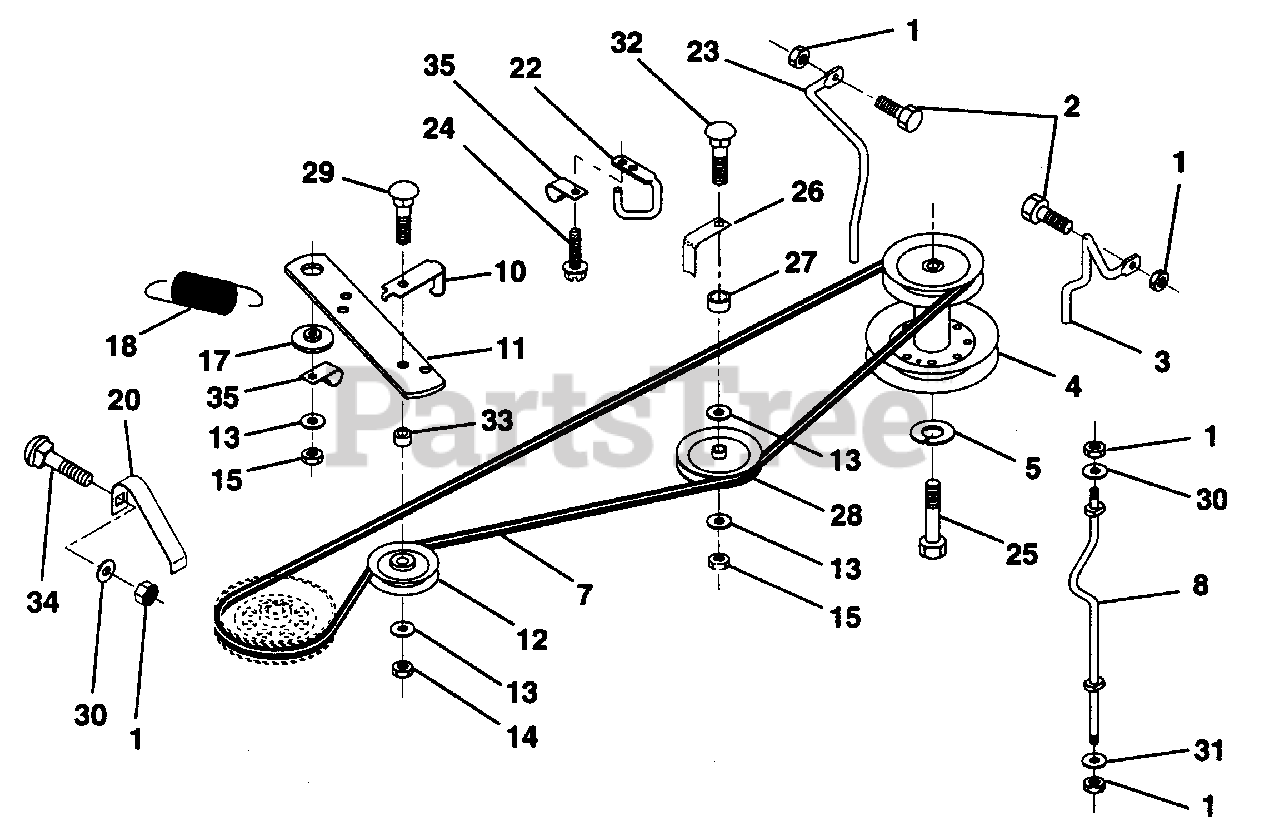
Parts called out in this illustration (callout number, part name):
1	Nut, Lock Hx w/Ins 5/16-18
2	Bolt, Hex Head 5/16-18 x 3/4
3	Keeper, Belt RH Front
4	Pulley, Engine
5	Washer, Lock 7/16
8	Keeper, Belt RH
10	Keeper, Belt, Idler Pulley
13	Washer 13/32 x 13/16 x 16 Gauge
14	Nut, Centerlock 3/8-16
15	Nut, Hex, Lock Hex w/wsh 3/8-16
17	Spacer, Retainer
18	Spring, Extension
20	Keeper, Belt LH
22	Keeper Frame Ground Drive Belt
23	Keeper, Belt LH Front
24	Screw, Thd. Cut 1/4-20 x 1/2
25	Bolt, Hex 7/16-20
28	Pulley, V-Idler
29	Bolt, RDHD SQ 3/8-16 x 2-1/4
30	Washer, Nut Lock Hex w/Ins. 5/6-18
31	Washer 11/32 x 3/4 x 16 Ga.
32	Carriage Bolt
34	Carriage Bolt
35	Clip Insulator
